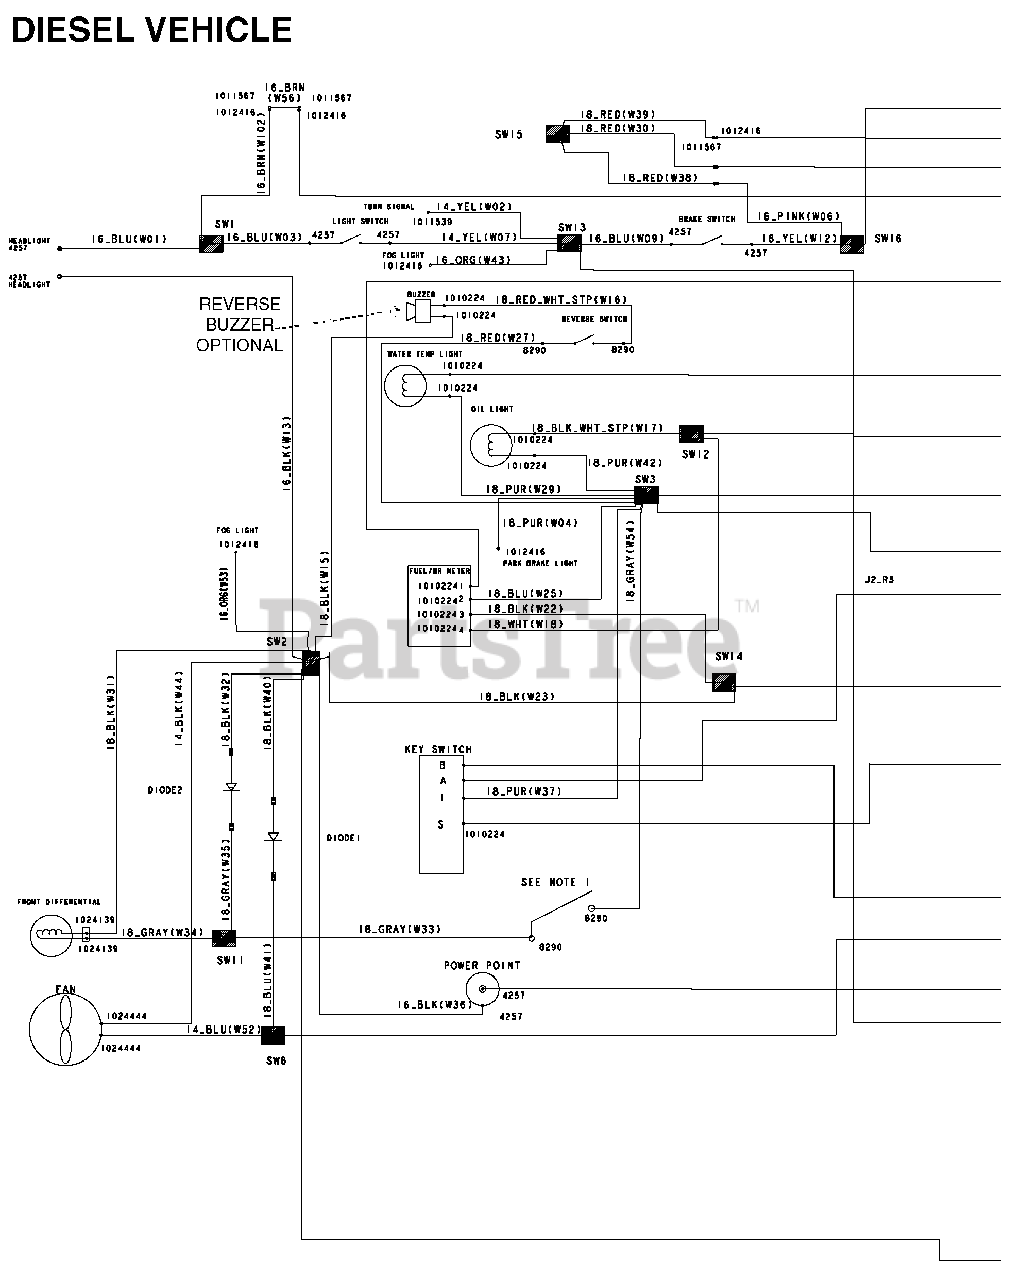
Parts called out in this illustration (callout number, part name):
1	Diode, General Purpose, 6.0a
2	Harness, Diesel, AWD, Stretch
3	Asm, Switch, Limit, Awd
